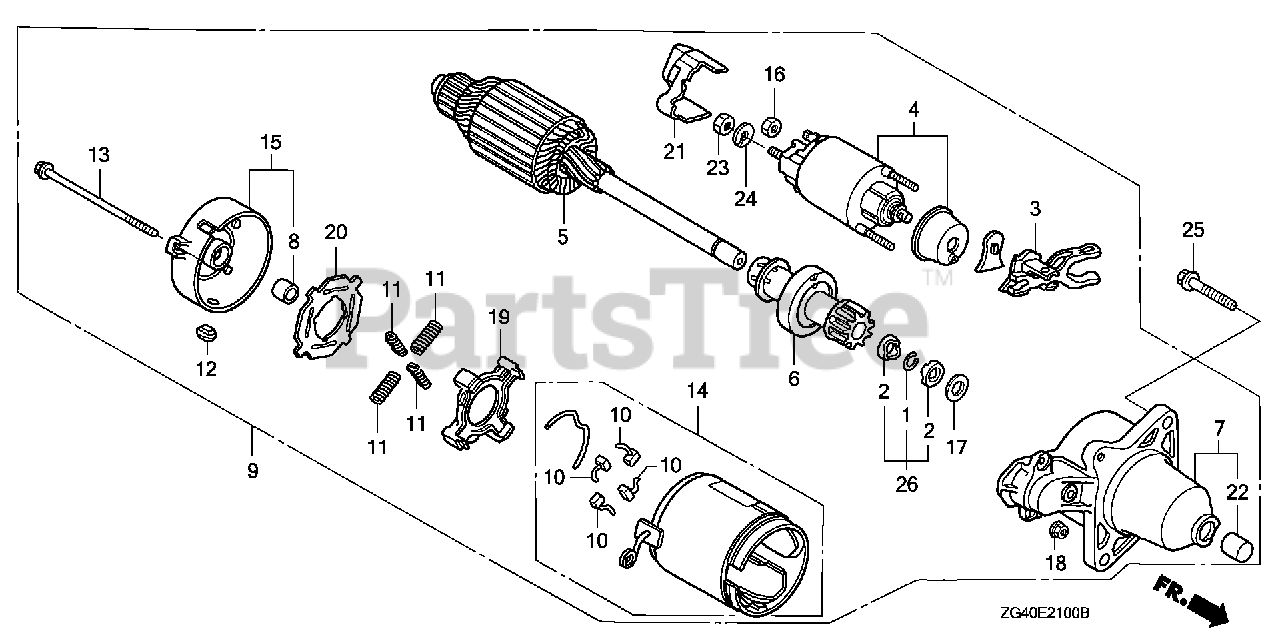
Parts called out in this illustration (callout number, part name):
1	RING, SNAP (DENSO)
2	COLLAR, CLUTCH STOP
2	COLLAR SET, CLUTCH STOP
3	LEVER, PINION DRIVE
4	SWITCH ASSY., MAGNETIC
6	CLUTCH, OVERRUNNING
7	HOUSING, DRIVE SIDE
9	STARTER MOTOR ASSY.
11	SPRING, BRUSH
13	BOLT, THROUGH
15	FRAME, COMMUTATOR END
16	NUT, HEX. (8MM)
19	HOLDER, BRUSH
20	INSULATOR, BRUSH HOLDER
21	COVER, TERMINAL
23	NUT, HEX. (8MM)
24	WASHER, SPRING (8MM)
25	BOLT, FLANGE (8X28)
